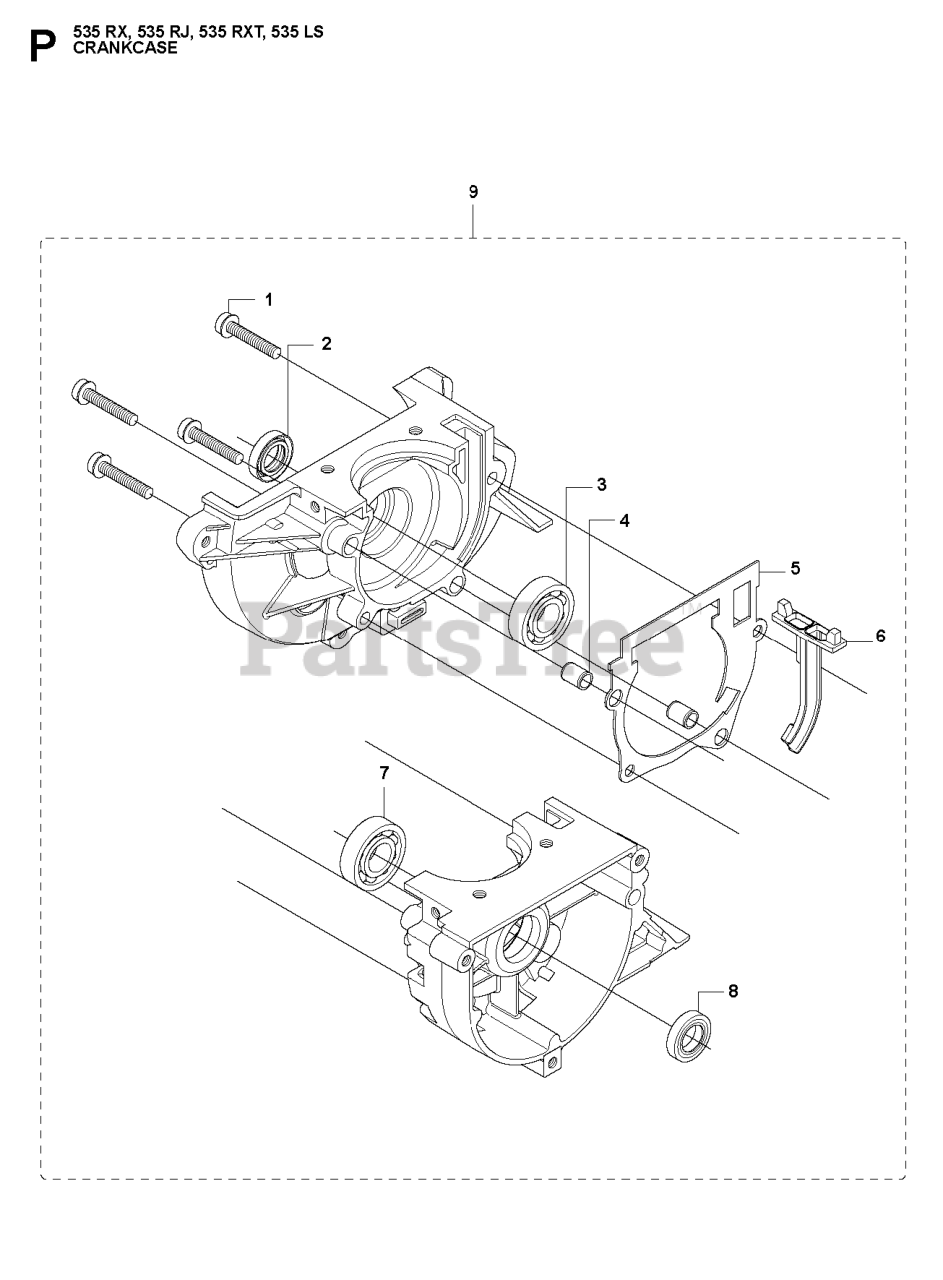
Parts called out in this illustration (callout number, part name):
2	SEALING RING
3	BALL BEARING
4	GUIDE BUSHING
5	GASKET CRANKCASE
6	INSERT, CARTER
7	BALL BEARING
8	SEALING RING
9	CRANKCASE CPL
